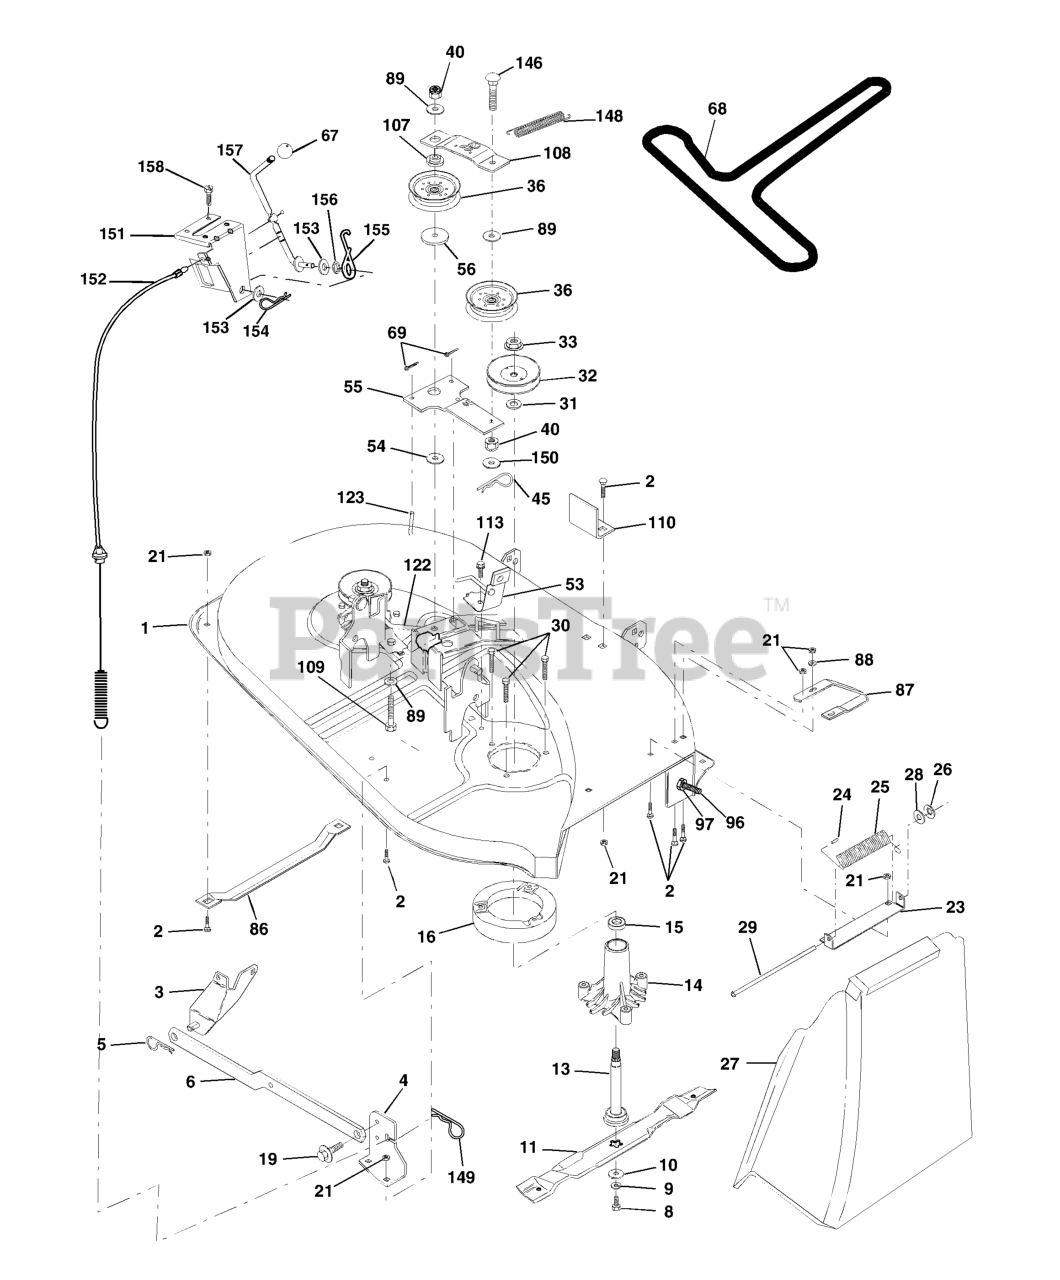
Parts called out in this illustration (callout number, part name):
1	MOWER HOUSING ASM
2	RP BOLT 5/16-18 X3/4 ZN/YEL GR
3	BRKT ASM SWAY BAR
4	BRACKET DECK SWAY BAR 38/42"
5	RETAINER-SPRNG RB
6	BAR SWAY DECK
8	BLADE BOLT
9	LOCKWASHER
10	WASHER.BLADE
11	BLADE.HI.LIFT.38"
13	SHAFT ASM VENT
14	HOUSING.MANDREL.VENTED (MACHD)
16	STRIPPER.MANDREL.ROUND.BLACK
19	BOLT SHD 5/16-18
21	LOCKNUT
23	BRACKET, DEFLECTOR
24	CAP-SLEEVE LT
25	SPRING TORSION
26	NUT PUSH M
27	SHIELD, DEFLECTOR
28	Washer 11/32 x 5/8 x 16 Gauge
29	ROD-HINGE T
30	SCREW, WASHER HEAD
31	WASHER
32	PULLEY MANDREL
33	NUT, FLG TOPLOCK 9/16"
36	FLAT IDLER PULLEY
45	RETAINER M
53	BRAKE ASSEMBLY
54	HARDENED WASHER
55	IDLER ARM
56	SPACER.RETAINER.MOWER
67	KNOB T (3/8 HOLE)
68	V-BELT TRIPATH
69	COTTER PIN
86	RUNNER-LH M
87	RUNNER.RH.38
88	WASHER M
89	WASHER GT
107	SPACER.IDLER.ARM
108	STIFFENER.IDLER.ARM
109	Bolt, Hex Hd 3/8-16 x 2-1/2
110	UPSTOP DECK FRONT 38"
113	SCREW 5/16"
122	BRAKE ROD LH
123	ROD.BRAKE.MANDREL.RH
146	BOLT, CARRIAGE IDLER
148	IDLER RETURN SPRING
149	SPRING.RETAINER.YELLOW.ZINC
150	WASHER PM
151	BRACKET.CLUTCH.CABLE
152	CLUTCH CABLE 38"/46"
153	WASHER FLAT 3/8"
154	SPRING RETAINER
155	SPRING RETENTION LEVER
156	SPACER.CLUTCH.CABLE
157	ROD CLUTCH CABLE 3/8"
158	SCREW
